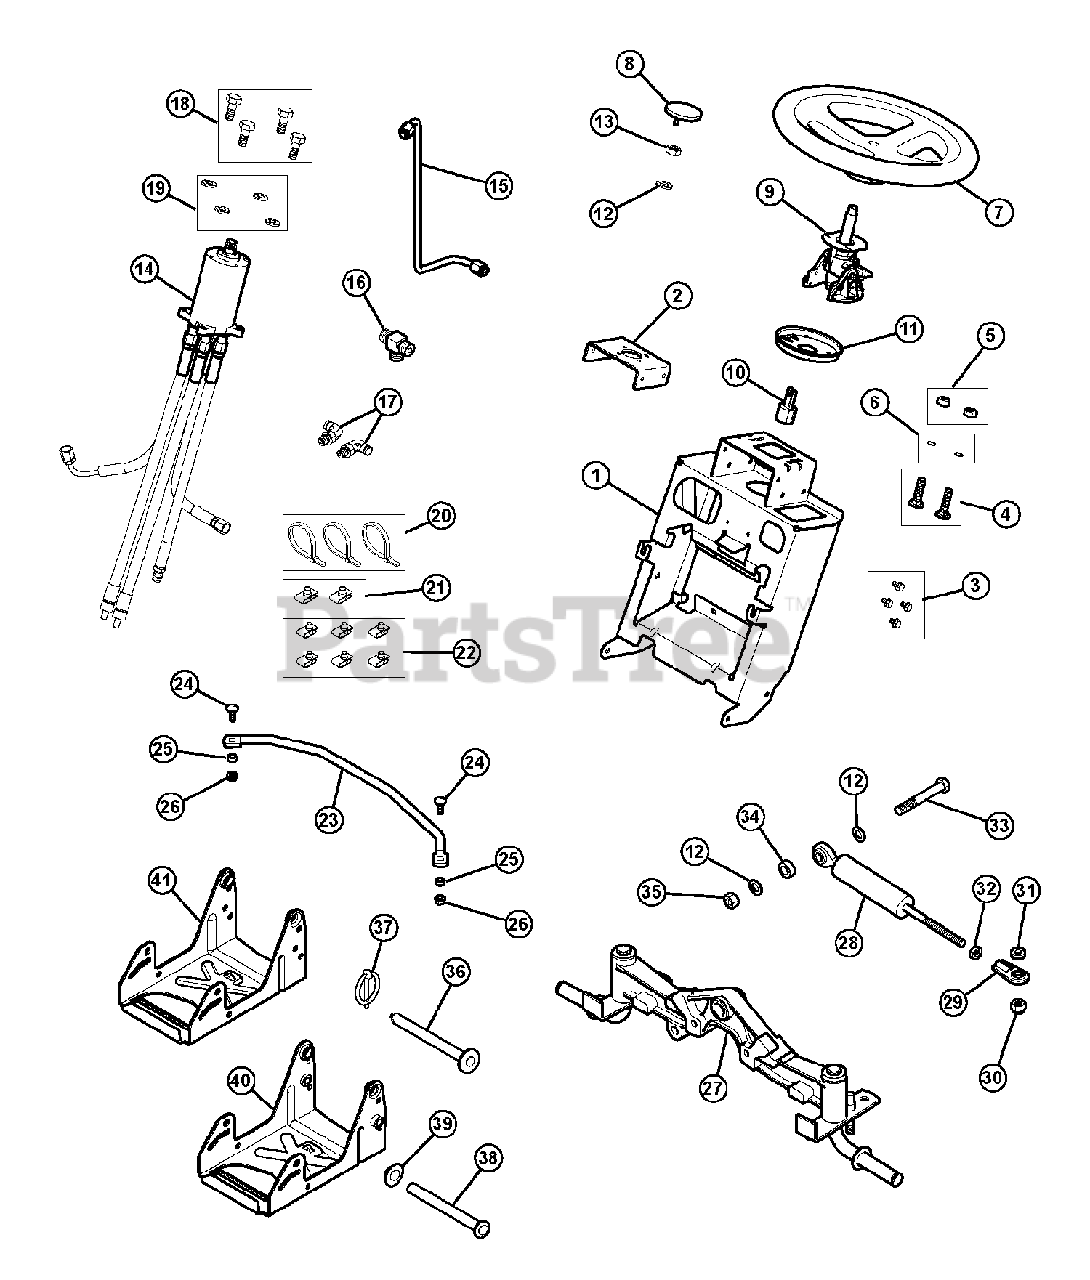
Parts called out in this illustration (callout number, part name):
1	TOWER, Steering
2	PLATE, Support
3	SCREW,Taptite 5/16-18 x 1/2
4	CARRIAGE BOLT, 5/16-18 x 1-1/4
5	NUT, KEPS, 5/16-18
6	NUT, Push, 5/16
7	STEERING WHEEL
8	CAP, Steering Wheel
9	TILT STEERING UNIT
10	ADAPTER, Tilt
11	PLATE, Mounting
12	WASHER, 5/8
13	NUT, HEX, 5/8-18
14	POWER STEERING Assembly, 5-Port
15	TUBE, Hydraulic
16	TEE FITTING
17	FITTING, Perma-Push
18	SCREW, HEX, M6 x 16mm
19	WASHER, LOCK, 1/4
20	TIE, Self Locking
21	NUT, SPEED, 5/16-18
22	NUT, SPEED, 1/4-20
23	TIE ROD
24	BOLT, 3/8-16 x 1
25	SPACER
26	NUT, Flange, Lock 3/8-16
27	FRONT AXLE Assembly
28	STEERING CYLINDER
29	BALL JOINT
30	NUT, Hex, Lock ESNA, 1/2-13
31	SPACER
32	NUT, Hex, Jam, 1/2-20
33	SCREW, Hex, M16-110mm
34	SPACER
35	NUT, Lock, 1/2-20
36	PIN, Hitch
37	PIN, Klik, 3/16 x 1-5/8
38	ROD, 1/2 x 7-5/8
39	NUT, PUSH, 1/2
40	HITCH, 54 Inch Mower
41	HITCH, 44/50 Inch Mower
